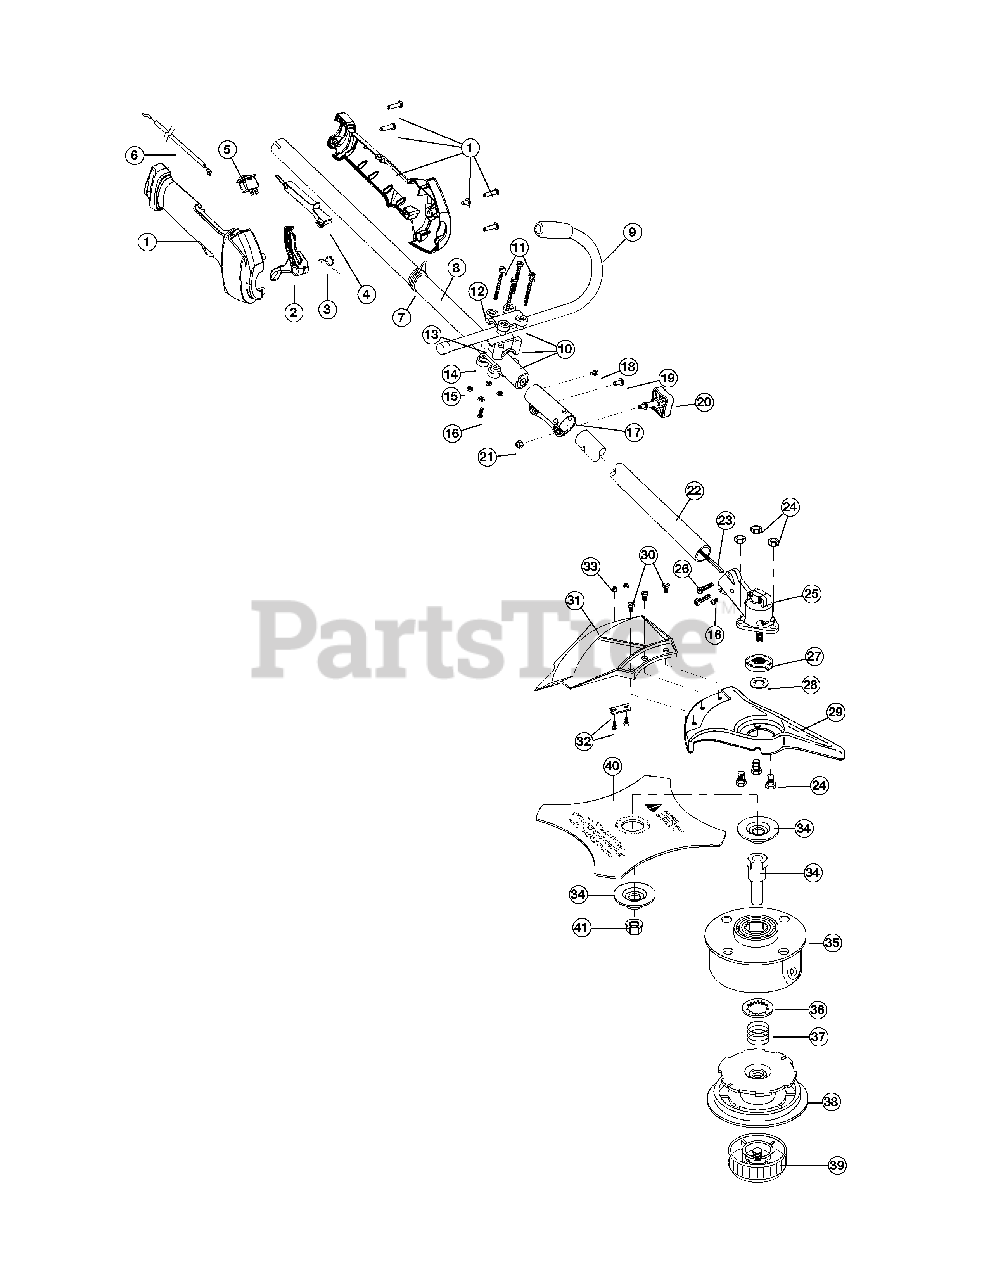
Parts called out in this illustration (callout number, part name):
1	Throttle Housing Assembly (Incl. Ref No. 2-5)
2	Throttle Trigger
3	Throttle Trigger Spring
4	Throttle Trigger Lock-Out
5	Switch Assembly
6	Throttle Cable Assembly
7	Harness Clip
8	Upper Drive Shaft Housing Assembly
9	J-Handle Assembly
10	Handle Bracket Assembly (Incl. Ref No. 11-16)
12	Upper Handle Clamp
13	Middle Handle Clamp
14	Lower Handle Clamp
16	Anti-Rotation Screw
17	Split Boom Coupler (Incl. Ref No. 18-21)
20	Adjustment Knob
21	Knob Retaining Nut
22	Lower Drive Shaft Housing Assembly
23	Lower Flexible Drive Shaft
24	Shield Mount Screw Assembly
25	Gearbox Assembly (Incl. Ref No. 16 & 26-28)
26	Gearbox Mounting Hardware
27	Blade Driver
29	Blade Shield/Shield Mount
30	Shield Mounting Screw
31	Shield Assembly (Incl. Ref No. 32)
32	Blade Assembly
33	Retaining Washer
34	Spool Shaft
35	Outer Spool Assembly
36	Retainer
39	Bump Head Knob Assembly
40	4-Tooth Blade
